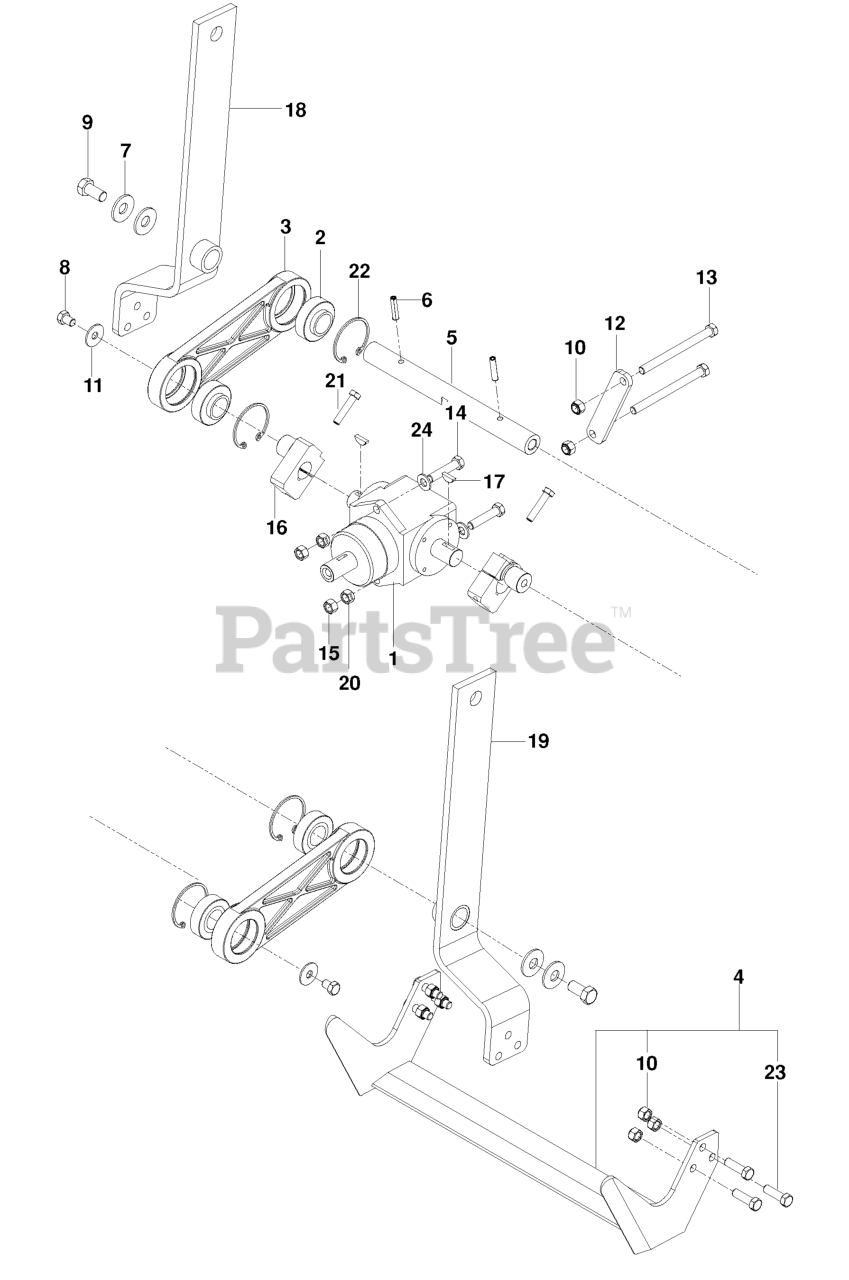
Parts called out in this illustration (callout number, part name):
1	GEAR BOX
2	BEARING
3	LINK - CONNECTING
4	KIT CUTTING BLADE 18" SOD CUT
5	SHAFT - BLADE ARM
6	SPIRAL PIN 1/4 DIA X 1.25
7	SPRING WASHER - .50
8	BOLT .375 X .5
9	HHCS 1/2-13 X 1
10	NUT 3/8-16 NYLOC
11	SPRING WASHER - .38
12	STRAP T-BOX BLACK
13	HCS 3/8C X 4 1/2
14	HCS 3/8-24
17	KEY, #9 WOODRUFF
18	BLADE ARM R.H., BLACK
19	BLADE ARM L.H., BLACK
20	NUT 3/8F CENTERLOCK
21	CAPSCREW 5/16 X 1/1/2 HEX HEAD
22	SNAP RING 52MM
23	HCS 3/8-16 X 1-1/4 GR 8 ZD
24	WASHER 3/8 SAE FLAT
